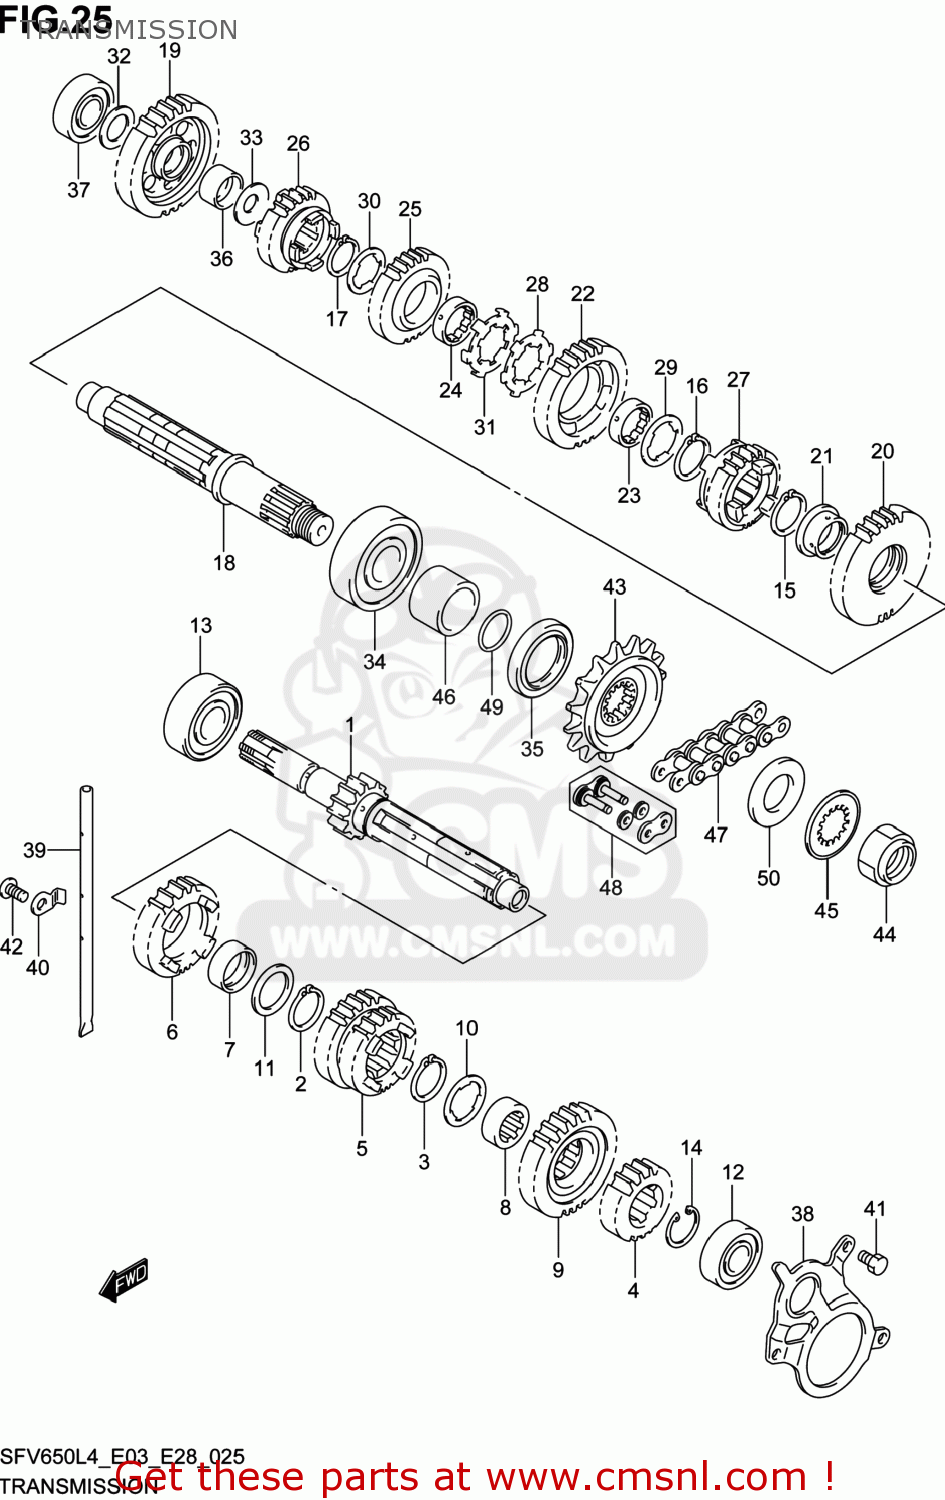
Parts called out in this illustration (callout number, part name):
1	SHAFT,COUNTER
2	CIRCLIP
3	CIRCLIP
4	GEAR,2ND DRIVE
5	GEAR,3RD & 4TH DRIVE
6	GEAR,5TH DRIVE(NT:26)
7	BUSH
8	BUSH,6TH DRIVE GEAR
9	GEAR,6TH DRIVE(NT:27)
10	WASHER,LOCK
11	SHIM(25X34X1)
12	BEARING(17X40X12)
13	BEARING(20X52X15)
14	CIRCLIP
15	CIRCLIP
16	CIRCLIP
17	CIRCLIP
18	SHAFT,DRIVE
19	GEAR,1ST DRIVEN
20	GEAR,2ND DRIVEN
21	BUSH,2ND DRIVEN GEAR
22	GEAR,3RD DRIVEN
23	BUSH,DRIVEN GEAR
24	BUSH,DRIVEN GEAR
25	GEAR,4TH DRIVEN
26	GEAR,5TH DRIVEN
27	GEAR,6TH DRIVEN
28	WASHER,LOCK
29	WASHER,LOCK
30	WASHER,LOCK
31	WASHER
32	SHIM(17X28X1)
33	SHIM(20X30X1)
34	BEARING(25X62X17)
35	SEAL,OIL(36X50X6)
36	BUSH(20X24X13)
37	BEARING(17X40X12)
38	RETAINER,DRIVE SHAFT OIL SEAL
39	GUIDE,T/M OIL
40	RETAINER,TRANSMISSION OIL
41	BOLT
42	SCREW
43	SPROCKET,ENGINE(NT:15)
44	NUT
45	WASHER,LOCK
46	SPACER,ENGINE SPROCKET
47	CHAIN,DRIVE(DID 520VM2)
48	JOINT SET,DRIVE CHAIN
49	O RING(D:2.4,ID:23.7)
50	WASHER
